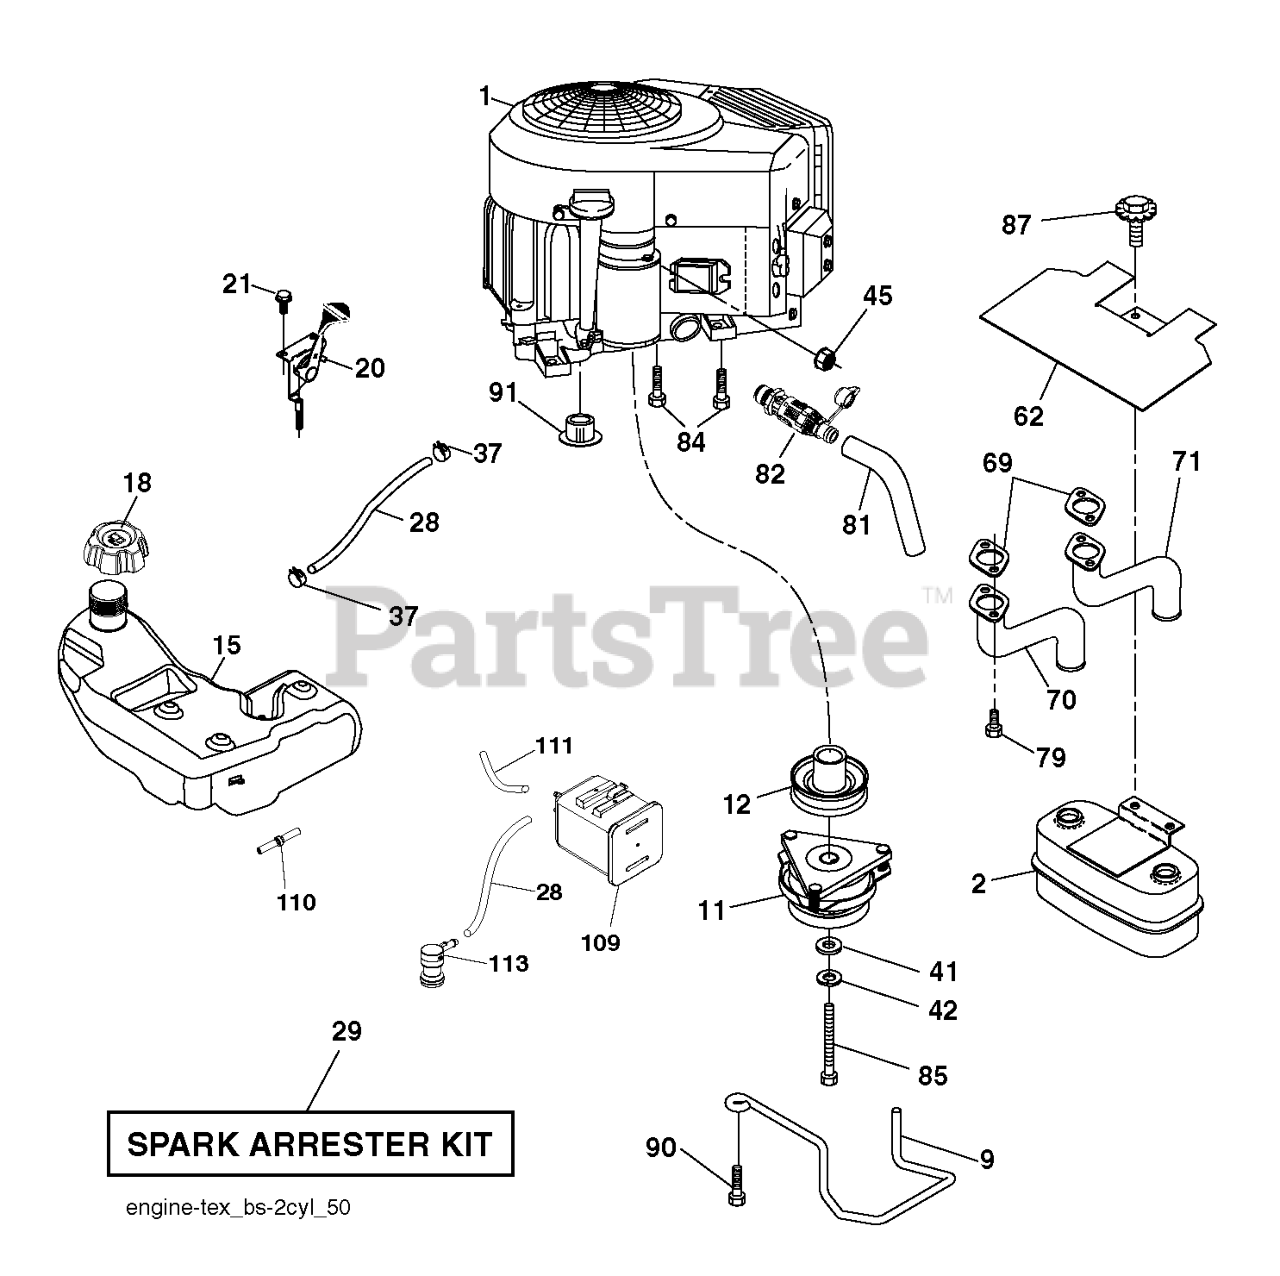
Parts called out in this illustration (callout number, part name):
2	MUFFLER.TWIN.CYL.LOW.TONE
9	KEEPER.BELT.ENGINE.4.2
11	CLUTCH.ELECTRIC.LT.48"*
12	PULLEY.ENGINE.TUFFTORQ
15	TANK ASM.FUEL.3
18	RP CAP ASM
20	CONTROL.TH/CK.COBRA.B&S.TWN.BK
21	SCREW.#10 X 0.750.BOS
28	LINE.FUEL.64"REAR.EMIS
29	KIT.SPARK ARRESTOR 794945 B&S
37	HOSE CLAMP
42	LOCKWASHER
45	NUT
62	SHIELD.HEAT.MUFFLER
69	GASKET.MUFFLER
70	EXHAUST.TUBE.LH.BS/TWIN
71	EXHAUST.TUBE.RH.B&S.TWIN.INTEK
79	SCREW.SOCKET.HEAD.5/16-18
81	TUBE, DRAIN OIL ASM.
82	VALUE.OIL.DRAIN
84	SCREW.3/8-16
85	BOLT HEX 7/16-20X4-1/4"
87	BOLT.5/16-18UNCX3/4 W/SEMS.BLK
90	SCREW 3/8-16X1
91	BUSHING.1.375OD
109	CANNISTER, CARBON
110	RP PURGE LINE
111	PURGE.LINE.36"REAR.CALIFORNIA
113	VALVE.SLANT.CARTRDG.90 DEG.TEX
